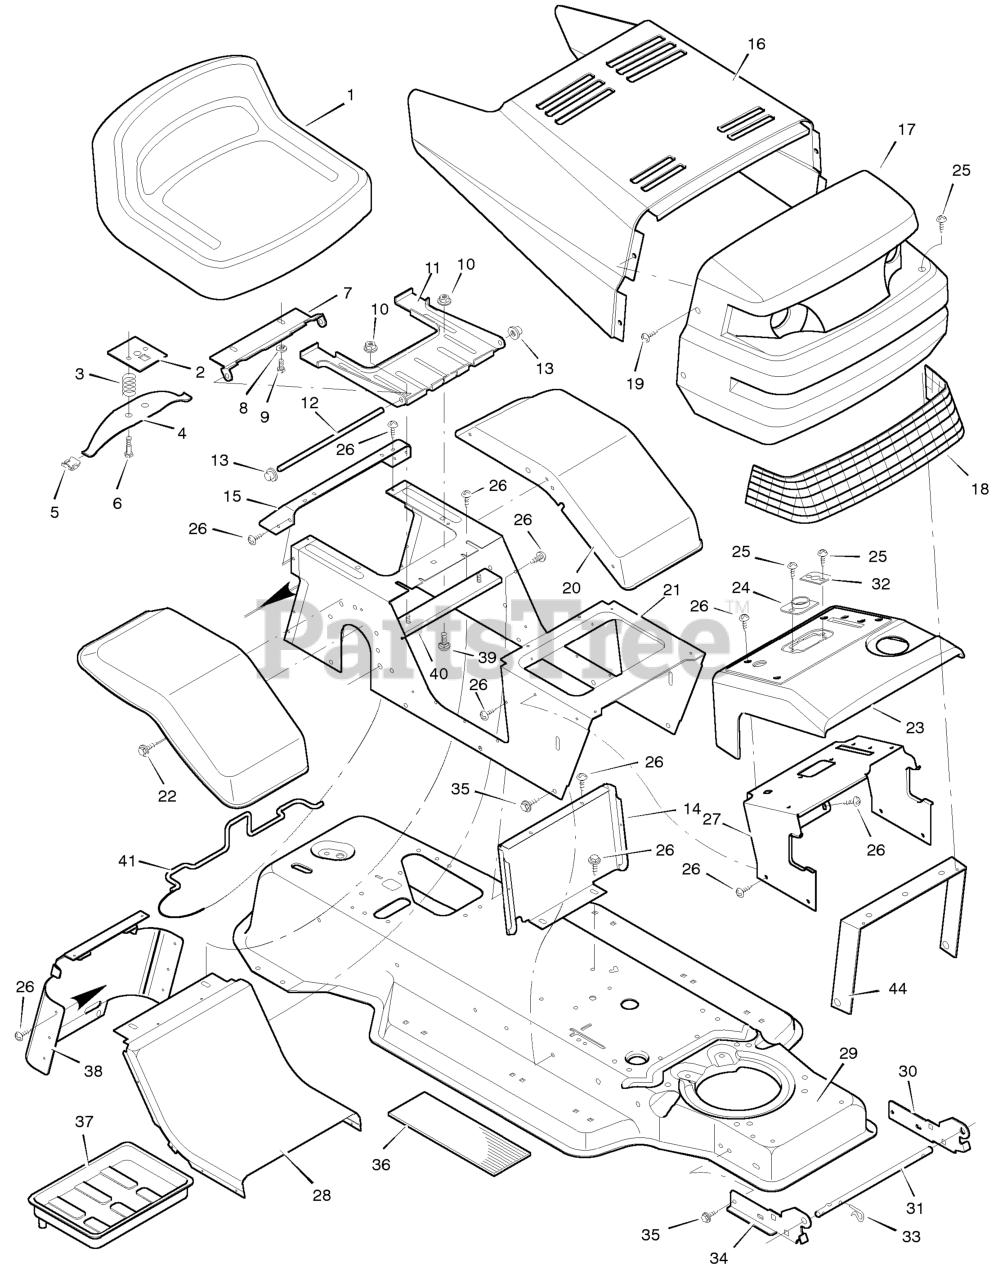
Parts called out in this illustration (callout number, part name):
2	Plate Assembly, Switch
3	Spring, Compression
4	Spring, Seat
5	Glide, Spring
6	Bolt, Shoulder
7	Support, Seat
8	Lockwasher
9	Bolt, Hex
10	Locknut, Flange
11	Bracket, Pivot
12	Rod, Pivot
13	Cap, Push On
14	Insert, Front
15	Fender, Apron
17	Grille Assembly
21	Console Assembly
23	Dash Panel
24	Bearing, Steering
26	Screw
27	Support, Dash
28	Insert, Rear
29	Frame Assembly
30	Bracket, Left Grille
31	Rod, Pivot
32	Bearing
33	Pin, Hair
34	Bracket, Right Grille
37	Tray, Battery
38	Cap, Console
39	Bolt
40	Channel Assembly
41	Clamp, Battery
44	Brace, Grille
46	Bolt, Hex
